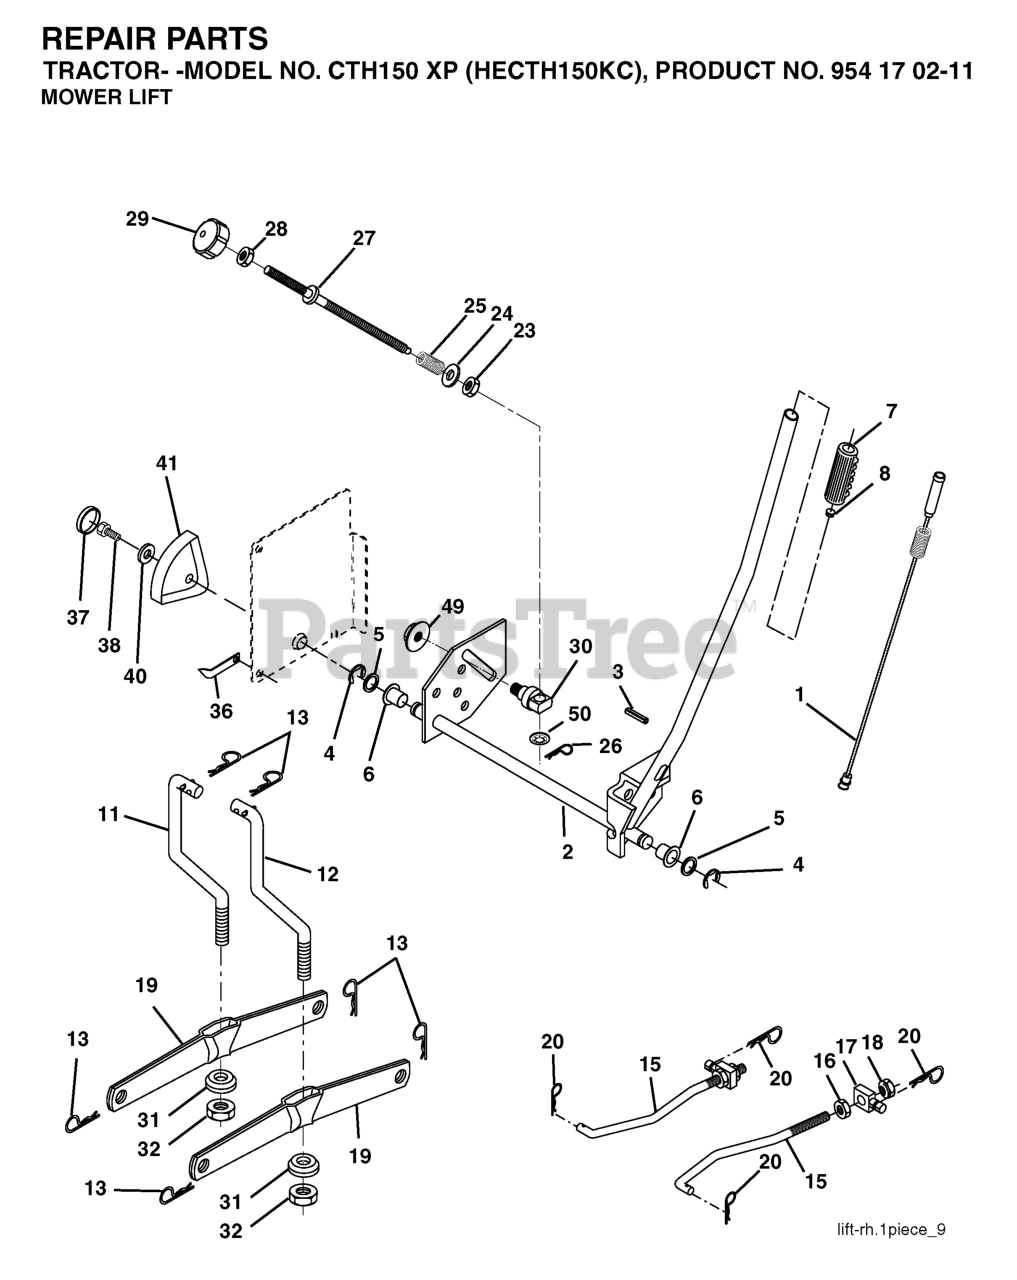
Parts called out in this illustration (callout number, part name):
1	WIRE ASM INNER W/ PLUNGER LT
2	SHAFT ASM R HANDLE
3	PIN GROOVE.
4	RETAINING RING LT
6	BEARING.NYLON
7	GRIP HANDLE
8	PLUNGER BUT KIT
11	LINK
12	LINK
13	RETAINER-SPRNG RB
15	LINK.SUSPENSION.FRONT
16	NUT.HEX.JAM.1/2-13
18	NUT.LK.W/WSH.1/2.
19	ARM.REAR.SUSPENSION
20	SPRING RETAINER
25	SPRING**
26	RETAINER CLIP
27	ROD ADJ LIFT
28	NUT
29	KNOB INF 3/8-16
31	BEARING.PIVOT.LIFT
32	NUT CROWNLOCK 3/8-24
36	POINTER, HEIGHT INDICATOR(2 2)
38	SCREW 5/16-18X1
41	HEIGHT INDICATOR
49	NUT
50	NUT PUSH M
